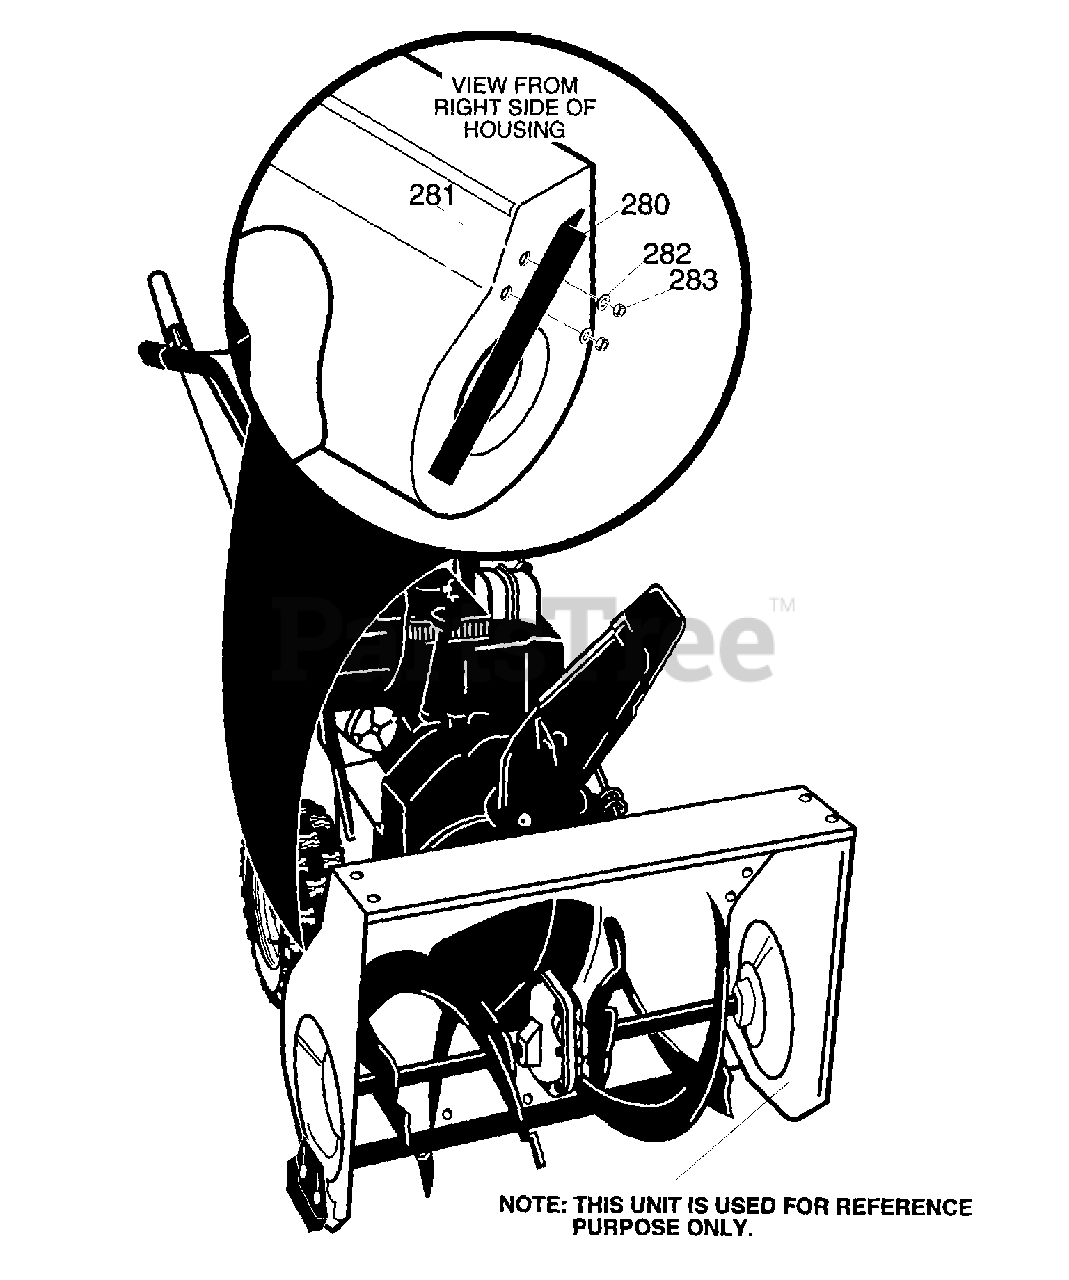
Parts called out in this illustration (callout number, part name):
280	BAR, DRIFT CUTTER
281	BOLT, 5/16-18 X .75
282	WASHER, HVSPTLK
283	NUT, 5/16-18 REGHEX
